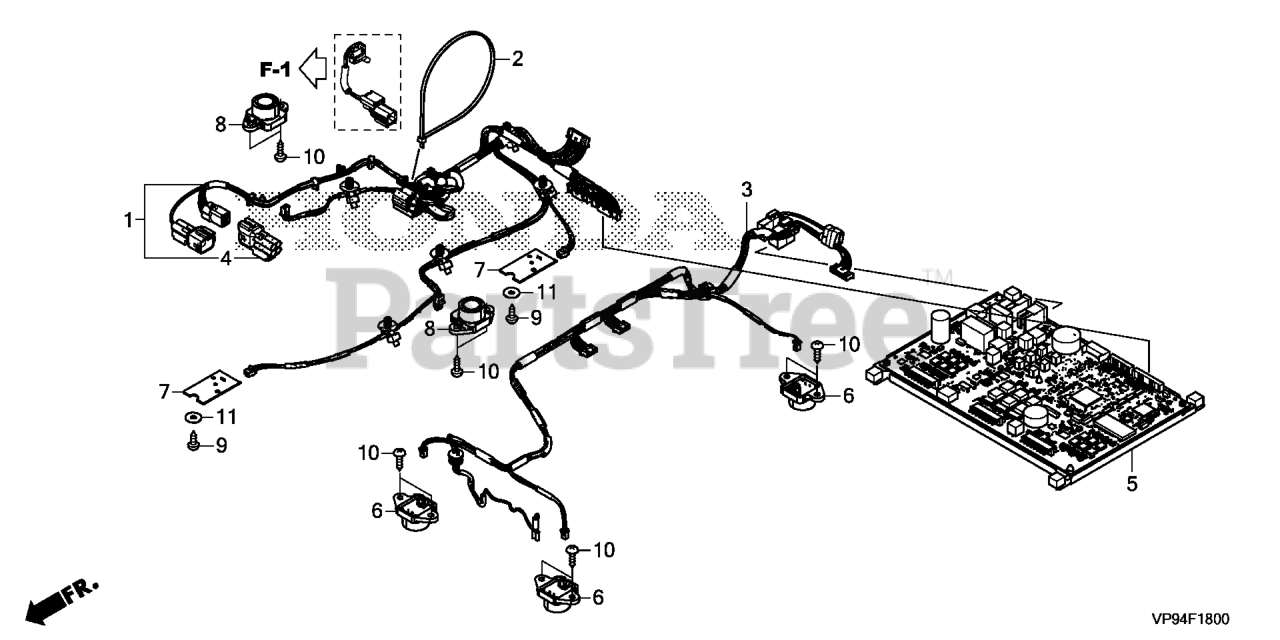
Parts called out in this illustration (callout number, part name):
1	WIRE HARNESS ASSY., MAIN
2	BAND, HARNESS
3	SUB-WIRE HARNESS ASSY.
4	CONNECTOR, DUMMY (4P)
5	CONTROL UNIT, ELECTRONIC
6	SENSOR ASSY., AREA
7	SENSOR, OBSTRUCTION
8	SENSOR ASSY., LIFT
9	SCREW, TAPPING (4X12)
10	SCREW, TAPPING (4X12)
11	WASHER, PLAIN (4MM)
